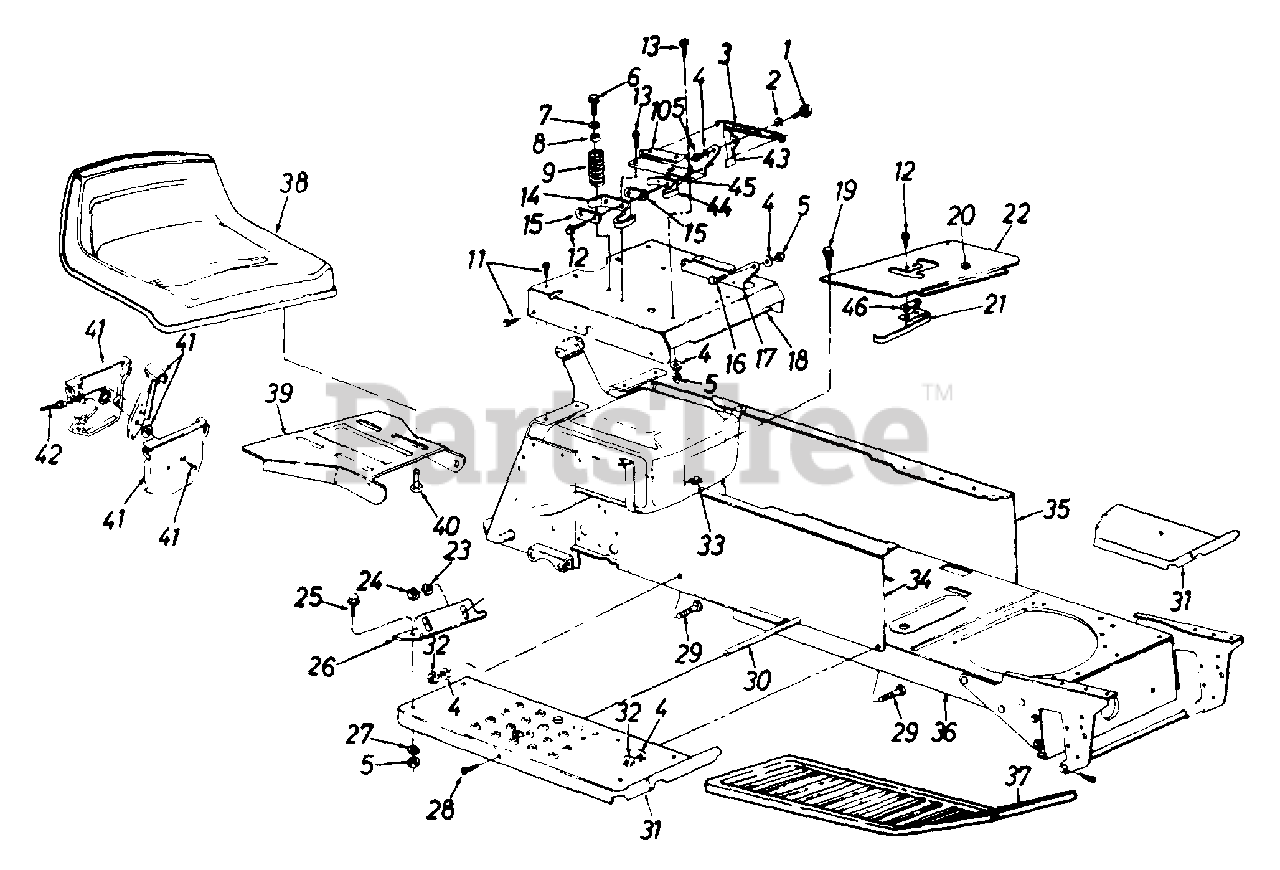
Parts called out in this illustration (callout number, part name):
1	Shld. Bolt .437" Dia. x .162"
2	Spr. Wash. .445" I.D.
3	Ext. Spring 5.31" Lg.
4	L-Wash. 5/16" I.D.
5	Hex Nut 5/16-18 Thd.
6	Hex Wash. Hd. Tap Scr. 5/16-18 x .7" Lg.
7	Fl-Wash. .344" I.D.
8	Bushing
9	Compression Spring
12	Hex Wash. Hd. AB-Tap Scr. #8 x .5" Lg
13	Torx Hd. AB-Tap Scr. 5/16-18 x .75" Lg.
14	Spring Switch
15	Insulator Plate
16	Shld. Bolt .437" Dia. x .162"
20	Snap Bushing
21	Reverse Safety Switch
22	Shift Cover
23	L-Wash. 1/4" I.D."
24	Hex Nut 1/4-20
25	Hex Bolt 5/16-18 x .75" Lg.
28	Truss Mach. Scr. 5/16-18 x .75" Lg.
29	Rib Neck Bolt 5/16-24 x 75" Lg.
30	Running Board Rod
33	Speed Nut #10Z
34	R.H. Side Frame
35	L.H. Side Frame
38	Seat 8-7/8" High
39	Seat Pivot Bracket
40	Hex Tap Scr. 3/8-16 x .75" Lg
41	Throttle Control Box Ass'y.
42	Throttle Control Wire 35" Lg
43	Seat Lift Bracket
44	Seat Spring Switch
45	Insulator Boss Plate
46	Insulator Nut Plate
